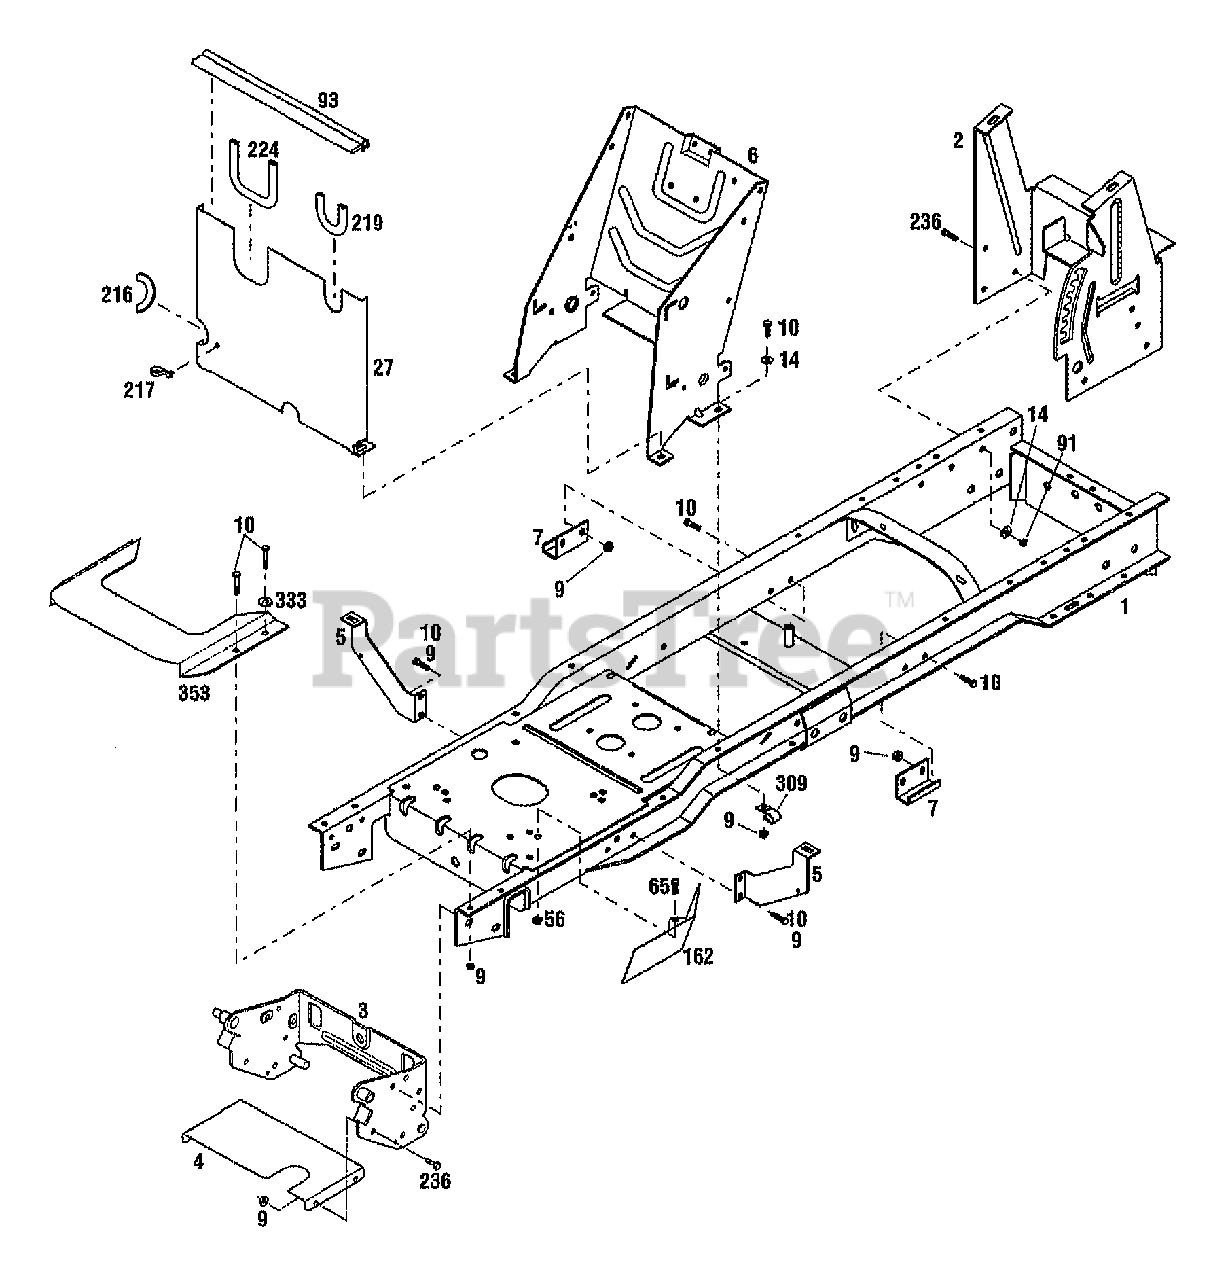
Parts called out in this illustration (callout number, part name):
2	SUPPORT-REAR TANK
3	ASSM-ATTACH BRACKET
4	SHIELD-HEAT
5	SUPPORT-FENDER {13103,13104}
5	SUPPORT-FENDER {13105}
6	SUPPORT-CONSOLE
7	STOP-MOWER DECK {13105}
9	NUT-HFLK 5/16-18 ZP
10	SCR-HHC 5/16-18X.75 GR 5 ZP
14	WASHER-FLAT 5/16 SAE
27	SHIELD-HEAT {13105}
56	NUT-HF/LK 1/4-20 ZP
65	SCR-HH 1/4-20X.625
91	NUT-TOP/LK 5/16-18 ZP
93	GASKET-HEAT SHIELD {13105}
162	SHIELD-HEAT UPPER {13105}
216	TRIM {13105}
217	HANGER-CABLE {13105}
219	TRIM {13105}
224	TRIM-HEAT SHIELD {13105}
236	SCR-HFLK 5/16-18X.75 ZP
309	CLIP-J
333	WASHER-1.5X.343X.104
353	SHIELD-HEAT {13105}
